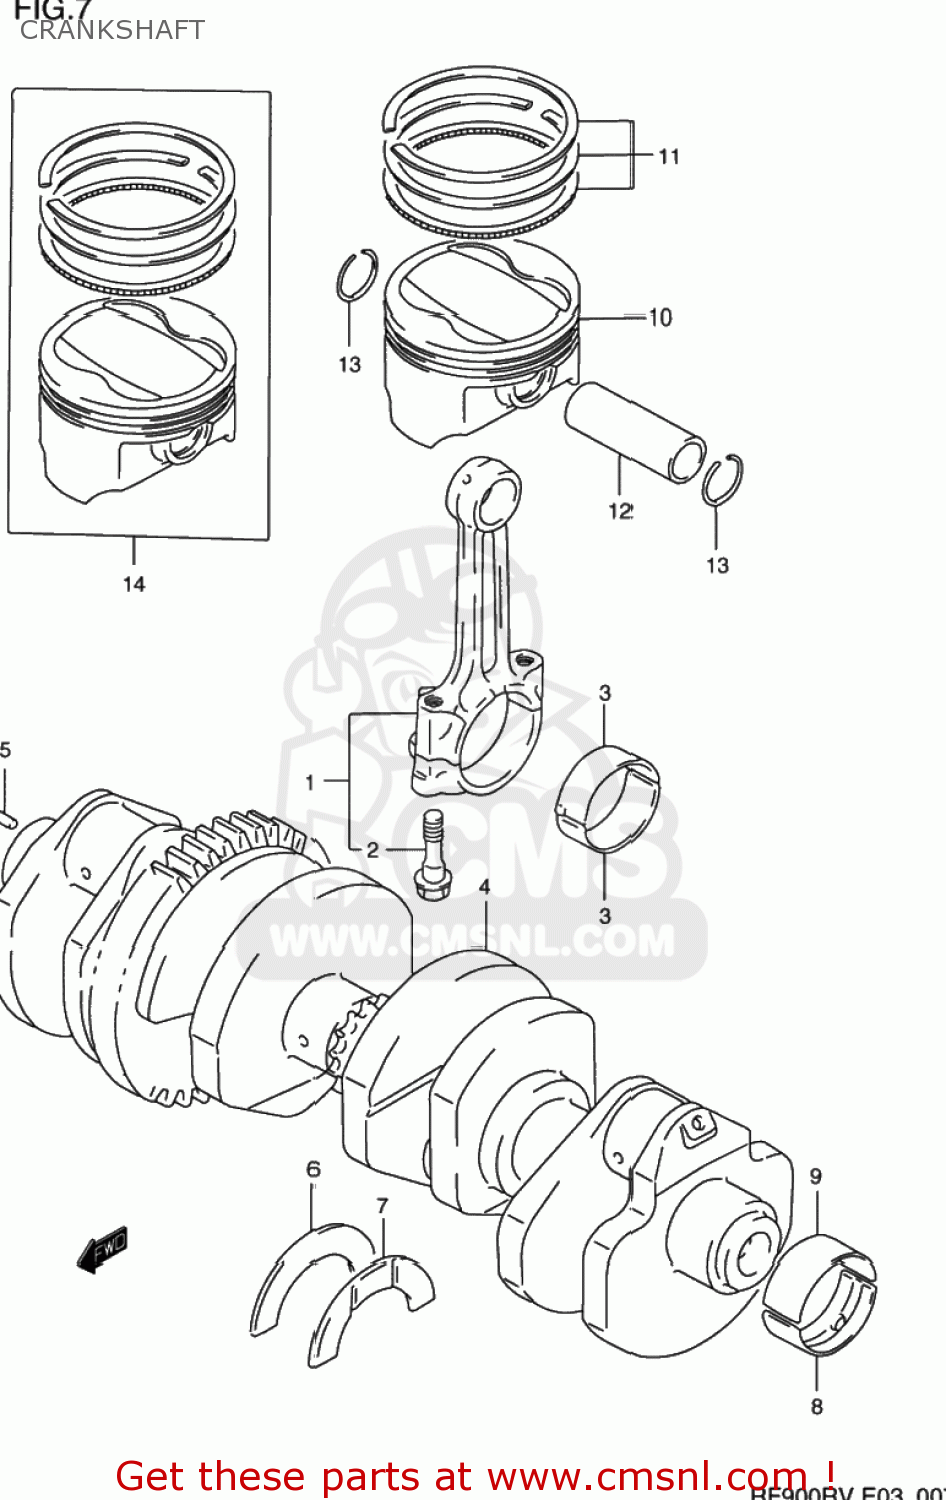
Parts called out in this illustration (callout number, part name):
1	CONNECTING ROD ASSY
2	BOLT,CONNCTING ROD
3	BEARING,CRANK PIN
4	CRANKSHAFT SET
5	PIN
6	BEARING,CRANK THRUST(GREEN)
7	BEARING,CRANK THRUST(RED)
8	BEARING,CRANKSHAFT LWR
9	BEARING,CRANKSHAFT UPR
10	PISTON (73.00MM)
11	RING SET,PISTON
12	PIN,PISTON
13	RING,SNAP
14	PISTON SET(OS:0.5)
